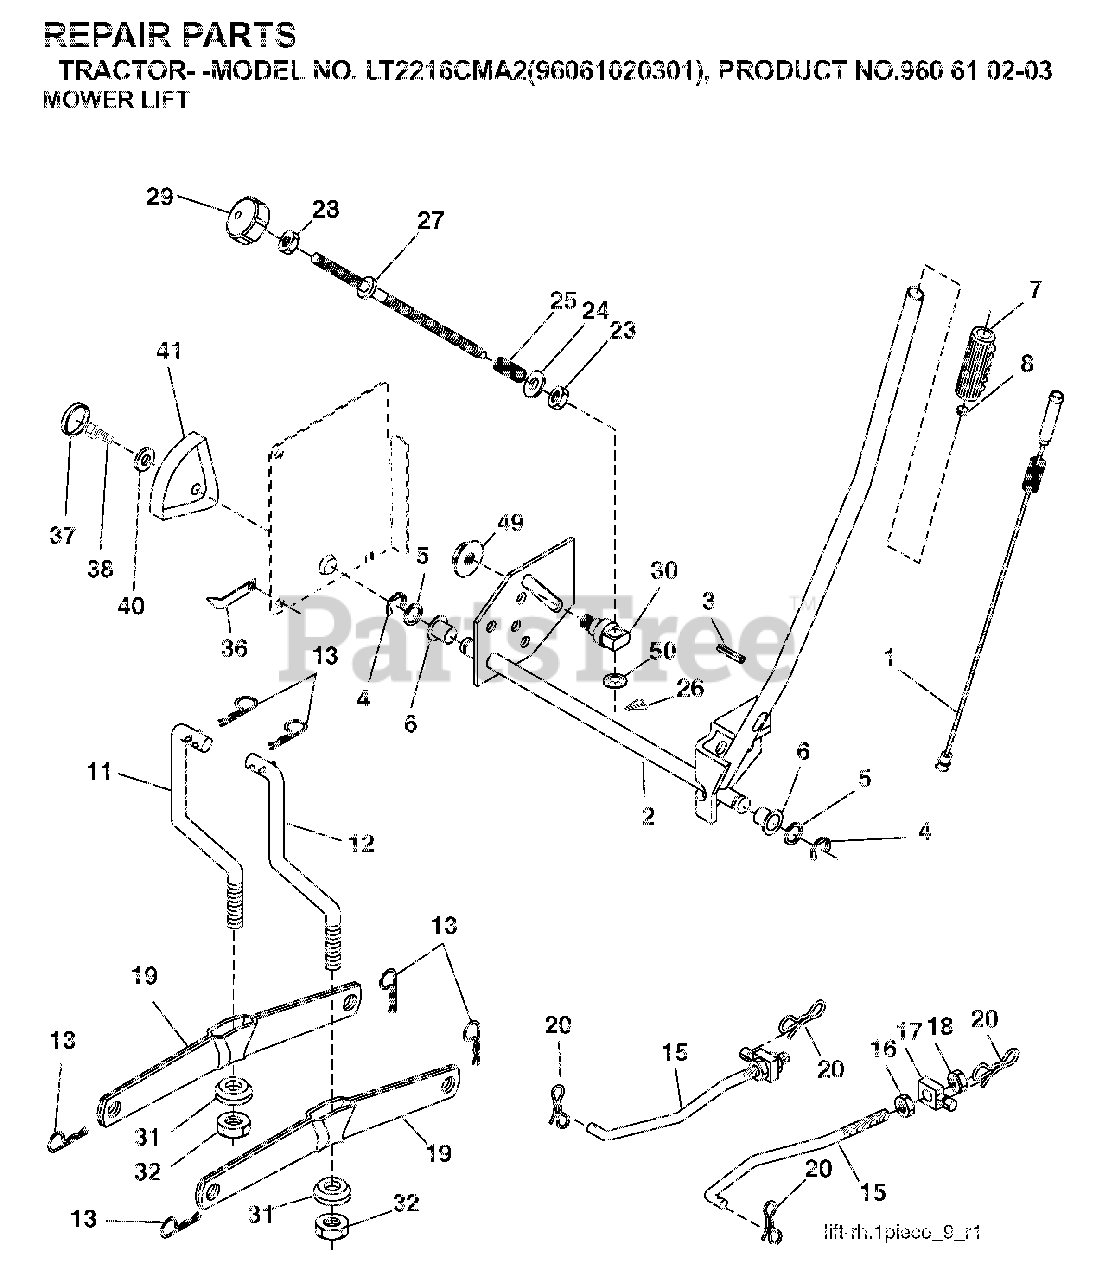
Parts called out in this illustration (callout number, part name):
4	RETAINING RING LT
6	BEARING.NYLON
7	GRIP HANDLE
8	PLUNGER BUT KIT
11	LINK
12	LINK
13	RETAINER-SPRNG RB
15	LINK.SUSPENSION.FRONT
16	NUT
18	NUT
19	ARM.REAR.SUSPENSION
20	PIN.COTTER.7/16.BOW TI
25	SPRING**
26	RETAINER CLIP
27	ROD ADJ LIFT
28	NUT
29	KNOB INF 3/8-16
31	BEARING.PIVOT.LIFT
32	NUT CROWNLOCK 3/8-24
36	POINTER, HEIGHT INDICATOR
37	PLUG,HOLE
38	SCREW 5/16-18X1
41	HEIGHT INDICATOR
49	NUT
50	NUT PUSH M
